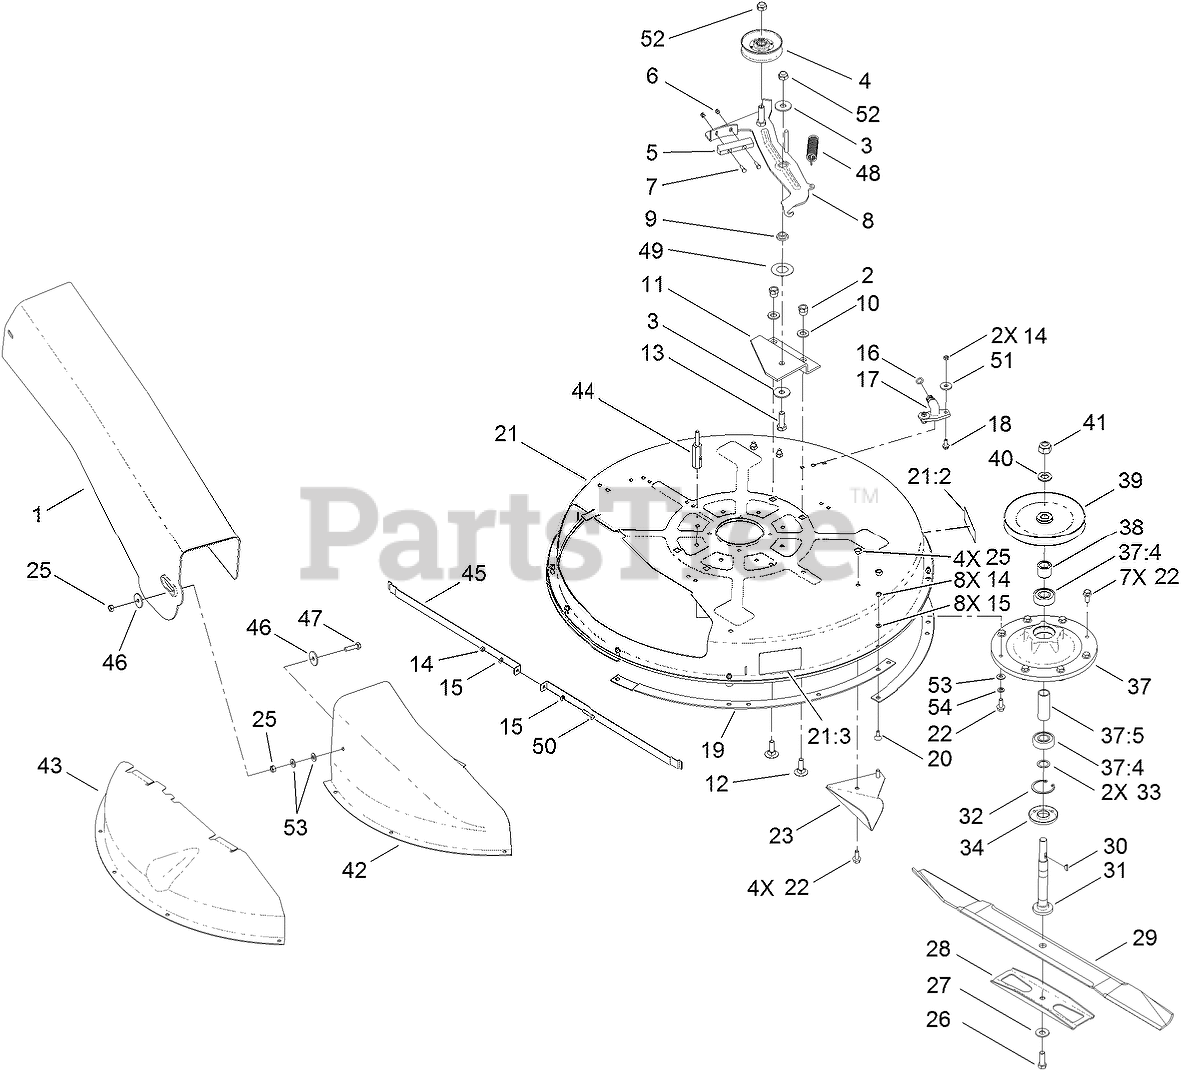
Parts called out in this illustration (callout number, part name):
1	Tube-Discharge
2	NUT-LOCK
3	Washer-Flat
4	PULLEY-IDLER
5	Brake-Rubber
6	NUT-LOCK
7	SCREW-HH
8	BRAKE ASM
9	Bushing
10	WASHER-FLAT
11	BRACKET-DECK
12	SCREW-CARR
13	SCREW-HH
14	NUT-LOCK
15	WASHER-FLAT
16	O-Ring
17	FITTING-WASHOUT
18	SCREW-HHF
19	RING-DECK
20	Screw-Sh
21	DECK ASM
21:2	Decal-Caution
21:3	DECAL-COVER, DISCHARGE
22	SCREW-HHF
23	Kicker
25	NUT-LOCK
26	SCREW-HH
27	Washer-Bell
28	STIFFENER
29	Blade-Recycler
31	SHAFT-SPINDLE
32	Ring-Snap
33	Spacer
34	SHIELD-BEARING
37	SPINDLE HOUSING ASM
37:4	BEARING-BALL
37:5	SPACER-BEARING
38	Spacer
39	PULLEY
40	WASHER-FLAT
41	Nut-Hex
42	Tunnel-Discharge
43	Cover-Recycler
44	Guide-Belt
45	STRAP-DECK
46	Washer-Flat
47	SCREW-HH
48	Spring-Extension
49	Spacer
50	SCREW-HH
51	Washer-Flat
52	Nut-Lock
53	WASHER-PLAIN
54	WASHER-LOCK
